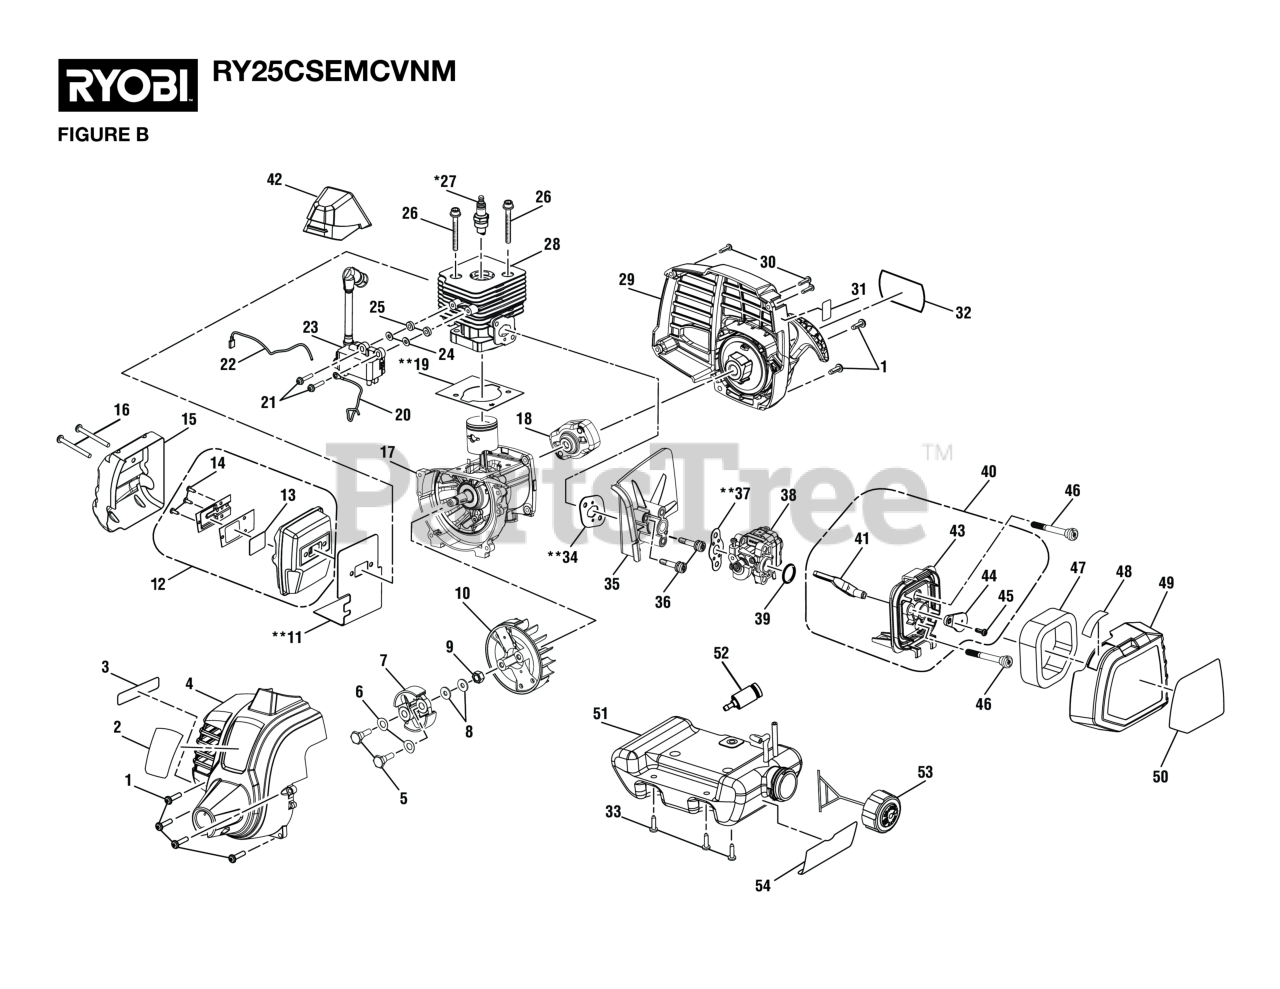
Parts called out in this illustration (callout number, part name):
1	Cap Screw w/Washer (M5 x 16 mm, T25 Torx Soc. Hd.)
2	Logo Label (Front)
3	Warning Label (Combustion)
4	Front Housing Assembly w/ Labels
5	Clutch Shoulder Bolt (M6 x 22.5 mm, Hex Hd.)
6	Washer (Curved)
7	Clutch Assembly
8	Washer (ID6 x OD15 x 1.2t)
9	Flange Nut (M8, Flywheel)
11	Muffler Gasket
12	Muffler Assembly
13	SCREEN
14	Screw (6-20 x 1/4 in., T20 Torx Pan Hd. S.T.)
15	HEAT SHIELD
16	Screw (M5 x 50 mm, Torx Slotted Recessed Pan Hd.)
17	Crankcase Assembly
18	Starter Cup
19	Gasket
20	Lead Wire Assembly, Red
21	Screw (M4 x 22 mm, T20 Torx Slotted Recessed Pan Hd.)
22	Lead Wire Assembly, Black
23	Coil Boot Assembly
24	Flat Washer (OD10 x ID42 x 1t)
25	Phenolic Spacer (Ignition Module)
26	Screw (M5 x 22 mm, T25 Torx Soc. Hd.)
27	SPARK PLUG CHAMPION - RCJ-6Y
29	Rear Housing and Starter Assembly
30	Screw (M4 x 20 mm, T20 Torx Pan Hd. S.T.)
31	Primer Bulb Location Label
32	Shoulder Screw (M4 x 14 mm, T25 Torx Truss Hd.
33	Shoulder Screw w/Washer (M4 x 14 mm, T25 Torx Truss Hd.)
34	Heat Dam Insulator
35	Screw (M5 x 30 mm, T25 Torx Pan Hd. S.T.)
36	Screw w/Washers (M5 x 30 mm, T25 Torx Pan Hd.)
37	Gasket
38	Carburetor Assembly
39	Carburetor O-Ring
40	Airbox Base Assembly
41	Compression Limiters
42	Spark Plug Boot
43	Air Box Base
44	Screw (M4 x 12 mm, T20 Torx Pan Hd. S.T.)
45	Screw (M4 x 12 mm, Slotted Recessed Pan Hd.)
46	Screw (M5 x 45 mm, T20 Torx Truss Hd.)
47	Air Filter (Element)
48	Choke Position Label
49	Airbox Cover (Inc. Key Nos. 48 & 50)
50	Starting Instructions Label
51	Fuel Tank and Cap Assembly
52	Fuel Filter
53	Fuel Cap Assembly
54	Fuel Mixture Label
